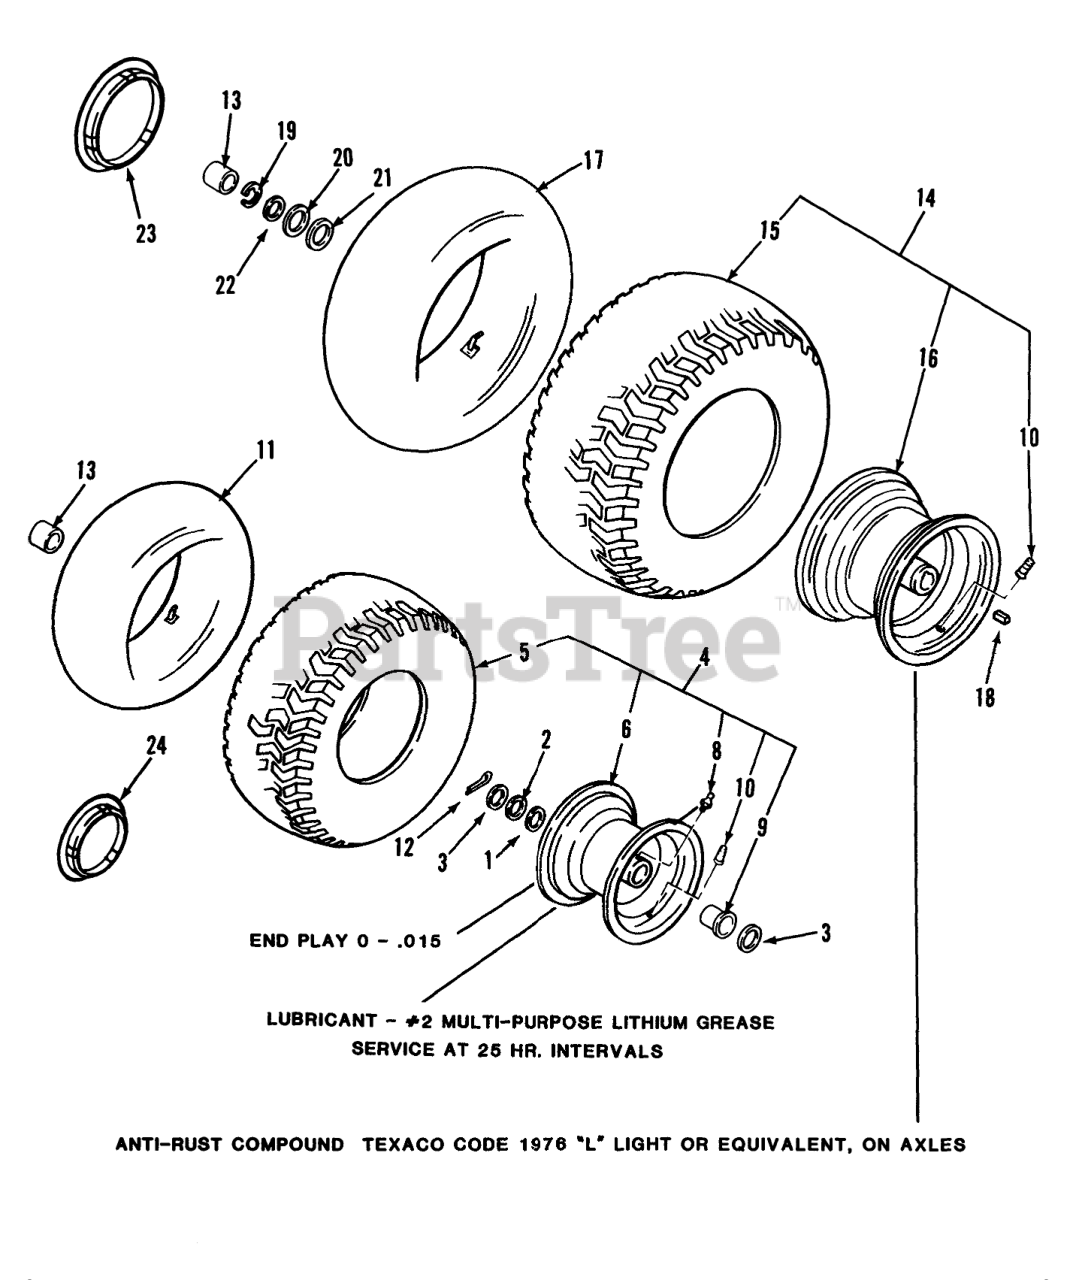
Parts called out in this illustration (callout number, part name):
1	WASHER-SHIM
2	WASHER
3	WASHER-FLAT
4	Front Wheel and Tire 15 x 6.00-6 (Includes items 5, 6, 8, 9 & 10)
5	TIRE-15 X 6.00-6
6	Front Wheel Assy (Includes Wheel with items 8,9, & 10)
8	ZERK-GREASE
9	BUSHING
10	VALVE
12	COTTER PIN-4
13	HUB CAP-FLAT BLACK
14	Rear Wheel & Tire-212-H
15	TIRE-18X9.50-8 TT RS
16	Rear Wheel
17	Tube-Inner
18	Key
19	Snap Ring
20	Washer
22	Washer
23	8"-HUB CAP LOGO
24	6"-HUB CAP LOGO
